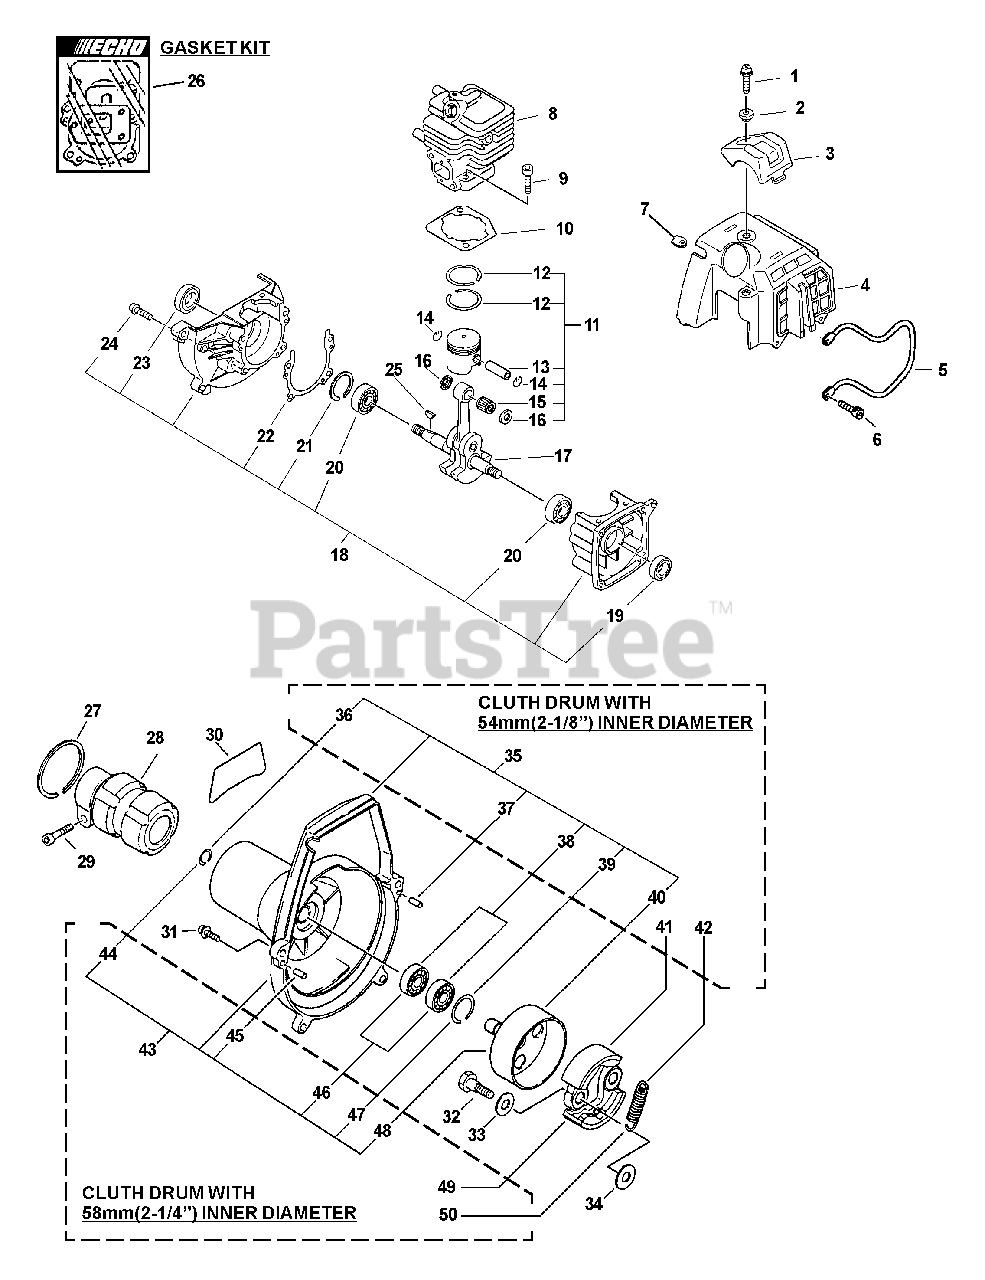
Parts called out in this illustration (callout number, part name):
1	SCREW 5×22
2	COLLAR 5
3	GUARD, TOP
4	COVER, CYLINDER
5	GUARD, ENGINE
6	BOLT 4×16
7	GROMMET, PLUG
8	CYLINDER
9	BOLT 5×22
10	GASKET, CYLINDER
11	PISTON KIT
12	RING, PISTON
13	PIN, PISTON
14	RING, SNAP
15	BEARING, NEEDLE
16	WASHER, THRUST
17	CRANKSHAFT ASSY
18	CRANKCASE KIT
19	SEAL, OIL 12
20	BEARING, BALL 6001
21	RING, SNAP 28
22	GASKET, CRANKCASE
23	SEAL, OIL 12
24	BOLT 5×25
25	KEY, WOODRUFF
26	GASKET KIT
27	RING, SNAP Ø42
28	HOLDER, MAIN PIPE
29	BOLT 5×28
30	LABEL, MODEL
31	BOLT 5×18
32	BOLT, CLUTCH 8×7.9×M6
33	WASHER, SPRING 8.5×16×0.5
34	WASHER 6.2×19×1.0
35	FAN CASE ASSY
36	RING, RETAINING - 12
37	PIN, LOCATING 4
38	BEARING, BALL 6001
39	RING, SNAP 28
40	DRUM, CLUTCH
41	SHOE, CLUTCH
42	SPRING, CLUTCH
43	FAN CASE ASSY
44	RING, RETAINING - 12
45	PIN, LOCATING 4
46	BEARING, BALL 6001
47	RING, SNAP 28
48	DRUM, CLUTCH
49	SHOE, CLUTCH
50	SPRING, CLUTCH
